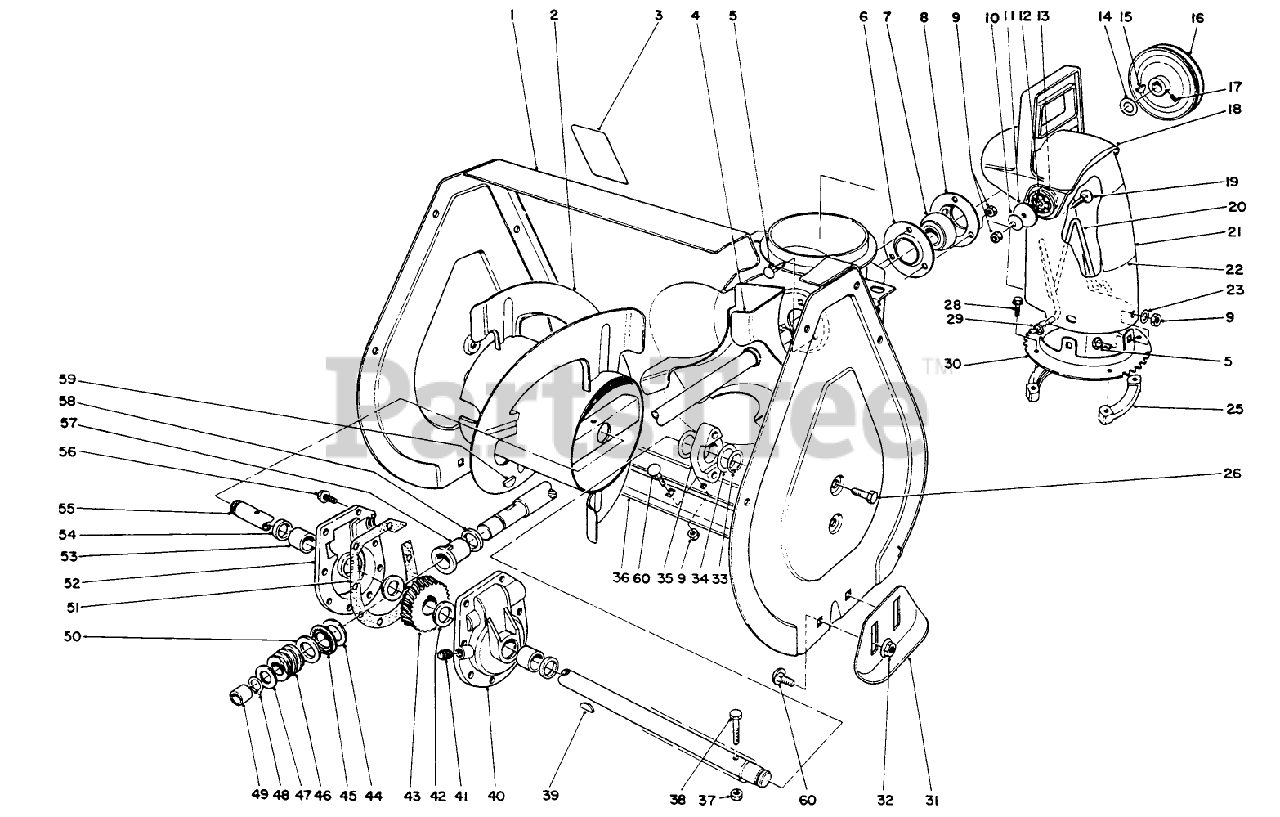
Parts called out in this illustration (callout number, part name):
1	Housing-Auger (Incl. ref. #3)
2	Auger-R.H.
3	DECAL-WARNING, AUGER
4	Shaft & Impeiler
5	SCREW-CARR
6	Flange-Bearing Front
7	BEARING-BALL
8	Flange-Bearing Rear
9	NUT-LOCK, NI
10	WASHER-BELLEVILLE
11	WASHER-FLAT
12	PLATE-FRICTION
13	WASHER-RUBBER
14	WASHER
15	KEY-WOODRUFF
16	PULLEY
17	SCREW-SET, SQH
18	CHUTE-DEFLECTOR
19	SCREW-CARR
20	WIRE-CHUTE
21	Chute-Discharge Model 38072 (Incl. Ref. #22)
22	Decal-Danger
23	WASHER-PLAIN
25	RING-CHUTE, RETAINER
26	SCREW-HWHTF
28	SCREW-SPECIAL
29	NUT-PUSH
30	Chute Ring
31	Skid
32	NUT-HF
33	RING-RETAINING
34	WASHER
35	BEARING-AUGER
36	Blade-Scraper
37	NUT-LOCK, NI
38	SCREW-HH
39	KEY-WOODRUFF
40	Gear Case L.H. (Incl. ref. #53 & 54)
41	PLUG-PIPE, SQH
42	WASHER-THRUST
43	GEAR-WORM, 27T
44	WASHER-THRUST
45	BEARING-THRUST
47	WASHER-THRUST
48	Ring-Snap
49	BUSHING
50	WASHER-THRUST
51	GASKET-CASE, GEAR
52	Gear Case R.H. (Incl. ref. #53 & 54)
53	BUSHING
54	SEAL-OIL
55	SHAFT-AUGER
56	SCREW-TAPTITE
57	BUSHING-INPUT
58	RING-QUAD
59	KEY-WOODRUFF
60	BOLT-CARR
